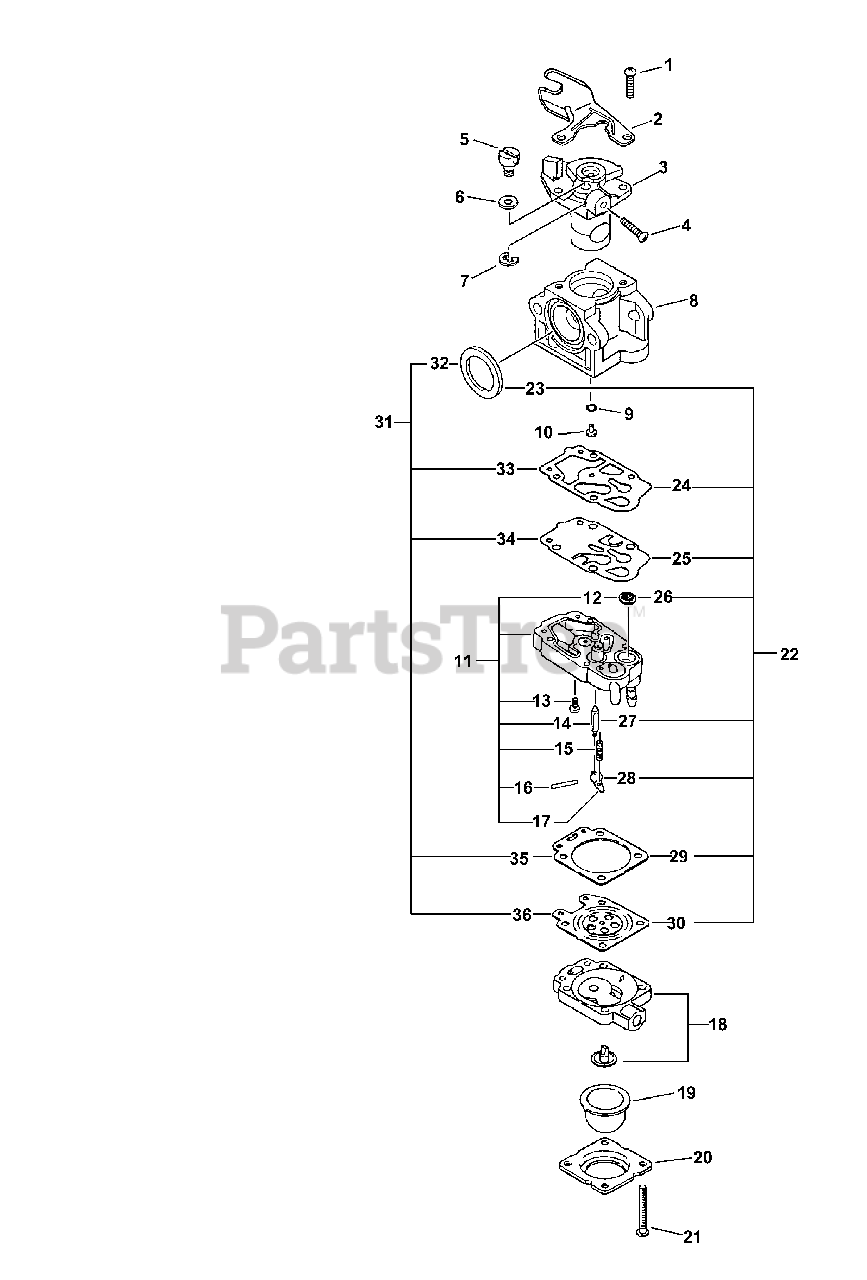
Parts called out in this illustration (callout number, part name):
2	BRACKET, CABLE
3	THROTTLE VALVE ASSY
4	SCREW, IDLE ADJUST
7	RING, RETAINING
8	BODY, CARBURETOR
11	BASE, PURGE
12	STRAINER
13	SCREW, METERING LEVER PIN
14	VALVE, INLET NEEDLE
15	SPRING, METERING LEVER
16	PIN, METERING LEVER
17	LEVER, METERING
18	PURGE BASE ASSY
19	BULB, PURGE
20	RETAINER, PURGE BULB
21	SCREW, PUMP COVER
22	REPAIR KIT
23	SEAL
24	GASKET, PUMP
25	DIAPHRAGM, PUMP
26	STRAINER
27	VALVE, INLET NEEDLE
28	LEVER, METERING
29	GASKET, METERING
30	DIAPHRAGM, METERING
31	DIAPHRAGM/GASKET KIT
32	SEAL
33	GASKET, PUMP
34	DIAPHRAGM, PUMP
35	GASKET, METERING
36	DIAPHRAGM, METERING
